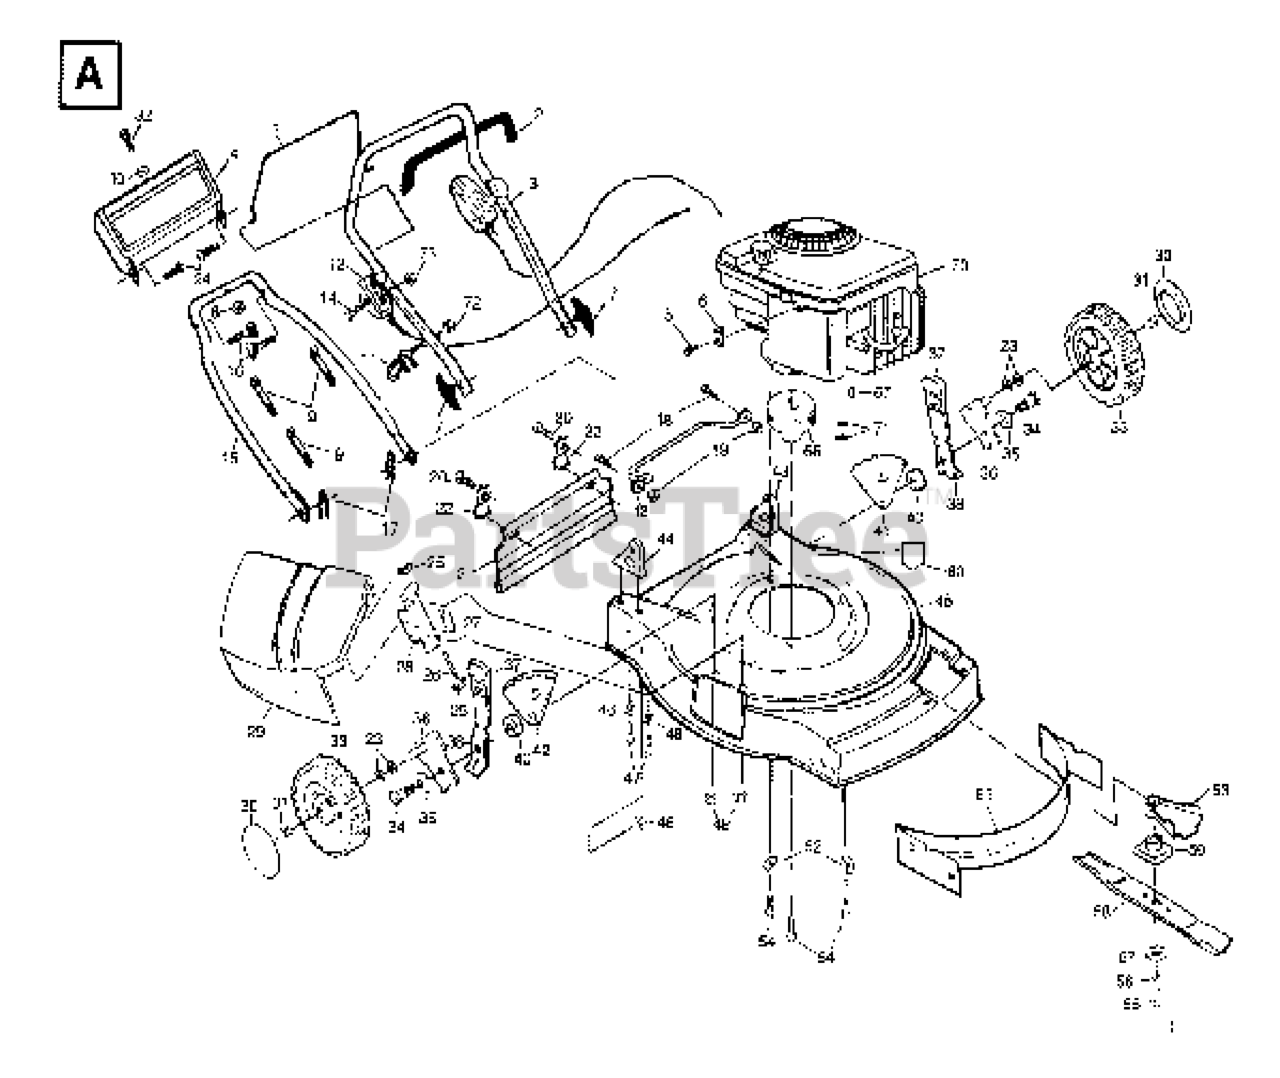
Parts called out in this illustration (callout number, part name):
1	CONTROL BAR
2	HANDLE GRIP
3	UPPER HANDLE
4	TRIM PLATE
5	SCREW.HEX.HEAD.WASHER.10-16
6	WASHER
7	HANDLE KNOB
8	NUT
9	TIE GUIDE
11	ROPE GUIDE
13	THROTTLE CONTROL
14	SCREW 1/4-20X1.75
15	HANDLE, LOWER PM
16	HANDLE BOLT
17	HAIRPIN COTTER
20	TAPPING SCREW
21	REAR SKIRT
22	BRACKET DEFL PM
23	WAVE WASHER
28	BRACKET PM
29	DISCHARGE GUARD
31	HEX FLANGE LOCKNT
32	SCREW
33	WHL & TIRE ASSEMBLY
34	BOLT
35	WASHER.BELLEVILLE (3 2 LB)
36	AXLE ARM ASSY FT
37	SELECTOR KNOB
40	SPACER PM
41	BRACKET WHL ADJ. NLA
42	BRACKET WHL ADJ
43	HANDLE BRKT ASSY LH
44	HANDLE BRKT ASSY RH
46	STEEL WASHER
47	SCREW
48	LOCKNUT PM
49	NUT
52	WASHER.ENGINE.BZP
53	DEBRIS SHIELD
54	BOLT
55	SCREW, HEX HD 3/8-24 X 1-3/8
56	LOCKWASHER
57	WASHER,HARDEN
59	BLADE ADAPTOR
66	ENGINE.PULLEY.FWG
67	HI PRO KEY PM WSL
72	NUT
73	NUT
